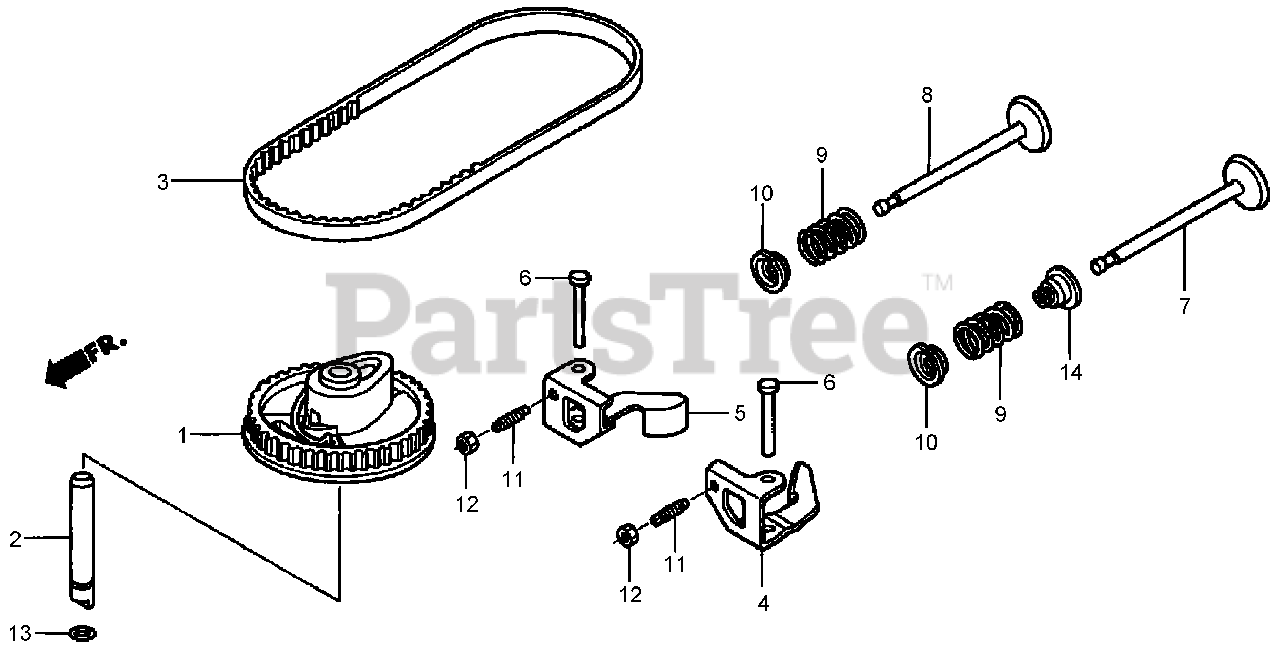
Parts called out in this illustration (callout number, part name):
1	PULLEY-CAMSHAFT
2	SHAFT-PULLEY
3	BELT-TIMING (84HU7 G-200)
4	ROCKER ARM-VALVE, INTAKE
5	ROCKER ARM-VALVE, EXHAUST
6	SHAFT-ARM, ROCKER
7	VALVE-INTAKE
8	VALVE-EXHAUST
9	SPRING-VALVE
10	RETAINER-SPRING, VALVE
11	SCREW-TAPPET, ADJ.
12	NUT-TAPPET, ADJ.
13	O-RING (6.8X1.9)
14	SEAL-STEM, VALVE
